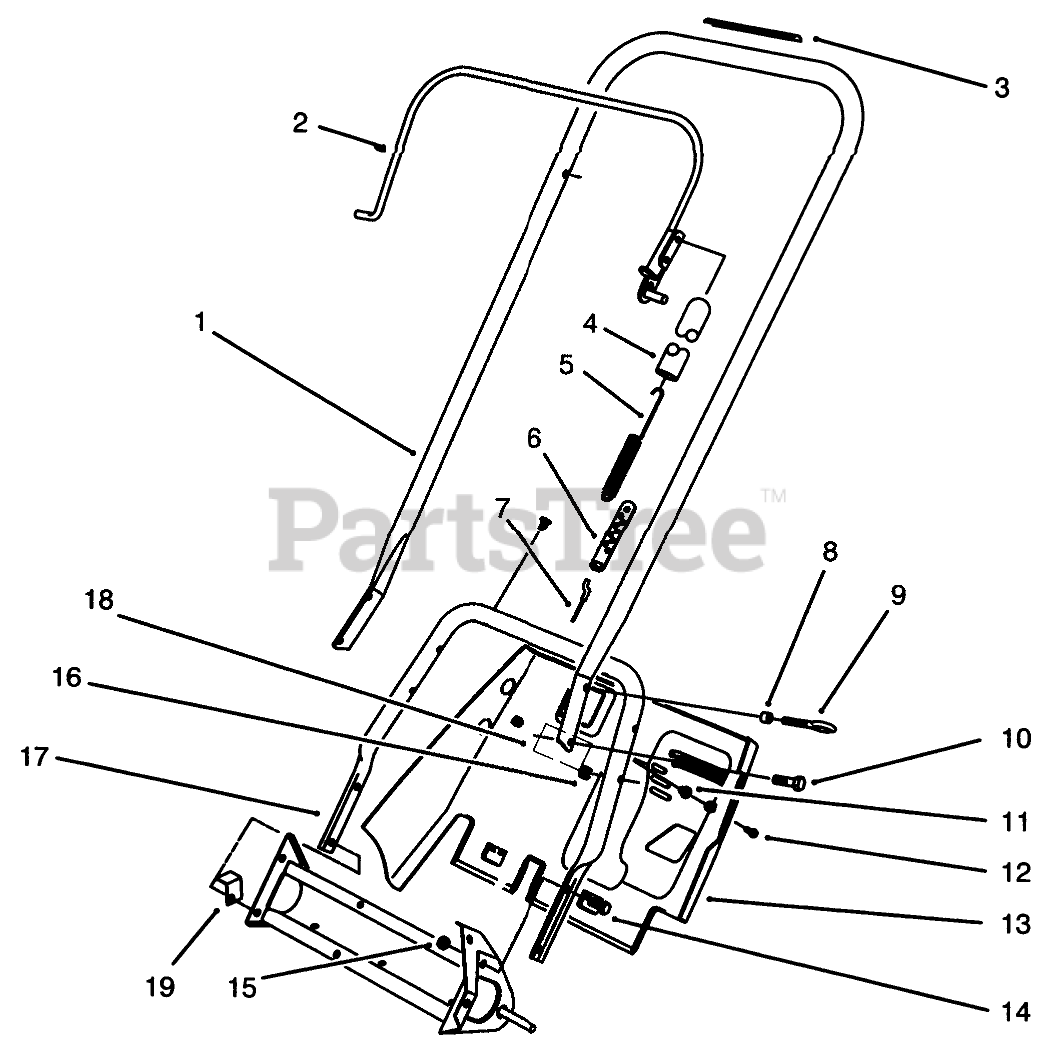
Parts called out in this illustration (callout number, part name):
1	Handle-Upper
2	Bail
3	DECAL-DRIVE, ROTOR
4	COVER-SPRING
5	SPRING-CLUTCH
6	ADJUSTER-CABLE, CLUTCH
7	CABLE-CLUTCH
8	SPACER-BLADE, ROTOR
9	EYEBOLT
10	SCREW-HEX HD SLOT
11	EXPANSION TYPE FASTENER
12	SCREW-SHWH, THREAD FORMING
13	LOWER SHROUD
14	SCREW-HH
15	NUT-LOCK, NI
16	TINNERMAN NUT
17	Handle-Lower
18	DECAL - WARNING
19	SHROUD BRACKET
